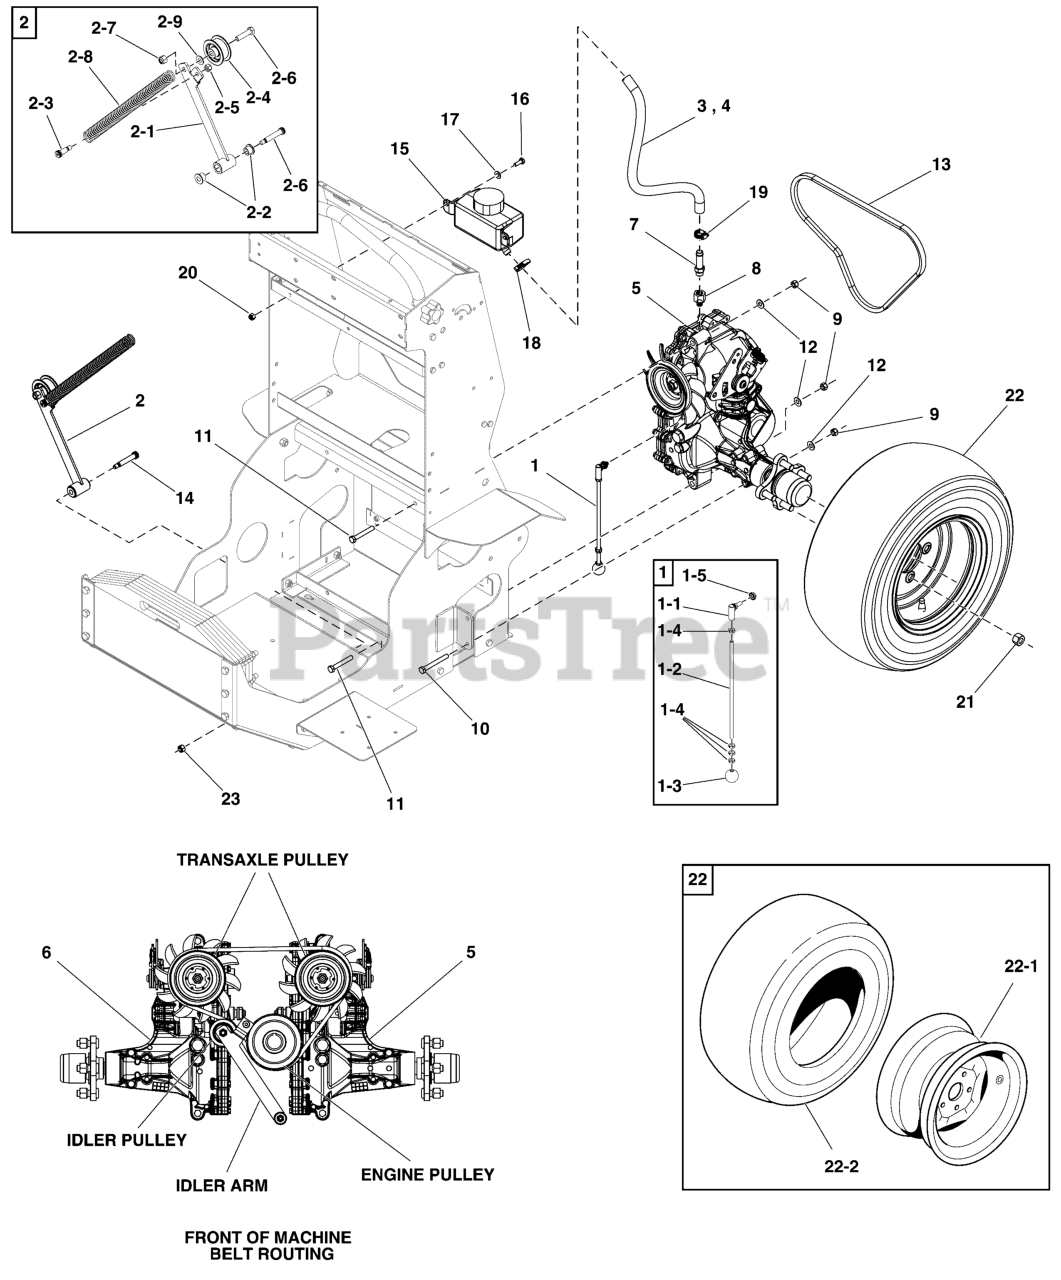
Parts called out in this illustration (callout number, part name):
1	ASM, TRANSMISSION RELEASE
1-1	ROD END, FEM 1/4-28 RH SS PTFE RACE STUD
1-2	ROD, CONTROL 1/4-28 THD X 9.00" MZ
1-3	KNOB, BALL 1.000 OD W/1/4-28 INSERT
1-4	NUT-HEX, JAM .250"-28 SS188
1-5	NUT-HEX-FGLK.250"-28 SS188
2	ASM, IDLER ARM
2-1	IDLER ARM W/ BUSHINGS
2-2	BUSHING, FLANGE 3/8 ID X 5/8 OD X 1/2 LG
2-3	BLT-SLDR, SH .375" X 0.750", .3125"-18 X.500" G8ZY
2-4	PULLEY IDLER 2.75" OD X 3/8" BORE
2-5	NUT-HEX-NYLK, .260"-20 TH SS188
2-6	SCR-CAP, HEX .375"-16 X 1.7500" SS188
2-7	NUT-HEX-NYLK, .375"-16 SS188
2-8	SPRING, SWIVEL HOOK, 9" X 1"
2-9	WSHR-STL, FLT .406" X .875" X .050" IS SS188
3	HOSE, L EXP TANK, 18.5" LONG
4	HOSE, R EXP TANK, 18" LONG
5	TRANSAXLE, ZT3100, LH, ZL-GMPP-3B7B-1PXX
5	TRANSAXLE, ZT3100, LH, ZL-GMPP-SB7B-1PXX
6	TRANSAXLE, ZT3100, RH, ZL-KMPP-3B7C-1PXX
6	TRANSAXLE, ZT3100, RH, ZL-KMPP-SB7C-1PXX
7	FITTING, 08HB - 06MORB STRAIGHT
8	FITTING, 6410-04-06
9	NUT-HEX-NYLK, 0.3125"-18 SS188
10	SCR-CAP, HEX .3125"-18 X 2.750" SS188
11	SCR-CAP, HEX .3125"-18 X 2.250" SS188
12	WSHR-STL, FLT .343" X .750" X .050" SPC SS188
13	BELT, V, AK36 38.00 OC OHR, KVR CD
14	BLT-SLDR SH.375"X1.75".3125"-18 X.50" SS188
15	HYDRO RES. # 71328, 350 ml
16	SCR-CAP, HEX .250"-20 X .750" SS188
17	WSHR-STL, FLT .281" X .625" X .050" IS SS188
18	SNAP GRIP CLAMP .656 - .750 ID
19	CLAMP, MINIATURE WORM GEAR MAH6
20	NUT-HEX-NYLK, .250"-20 SS188
21	NUT-LUG, .500"-20 ZP
22	ASM, WHEEL & TIRE 20" X 8.00" - 10 TURF
22-1	WHEEL ONLY
22-2	TIRE, 20" X 8.00" - 10 TURF
23	NUT-HEX-NYLK, .260"-20 TH SS188
